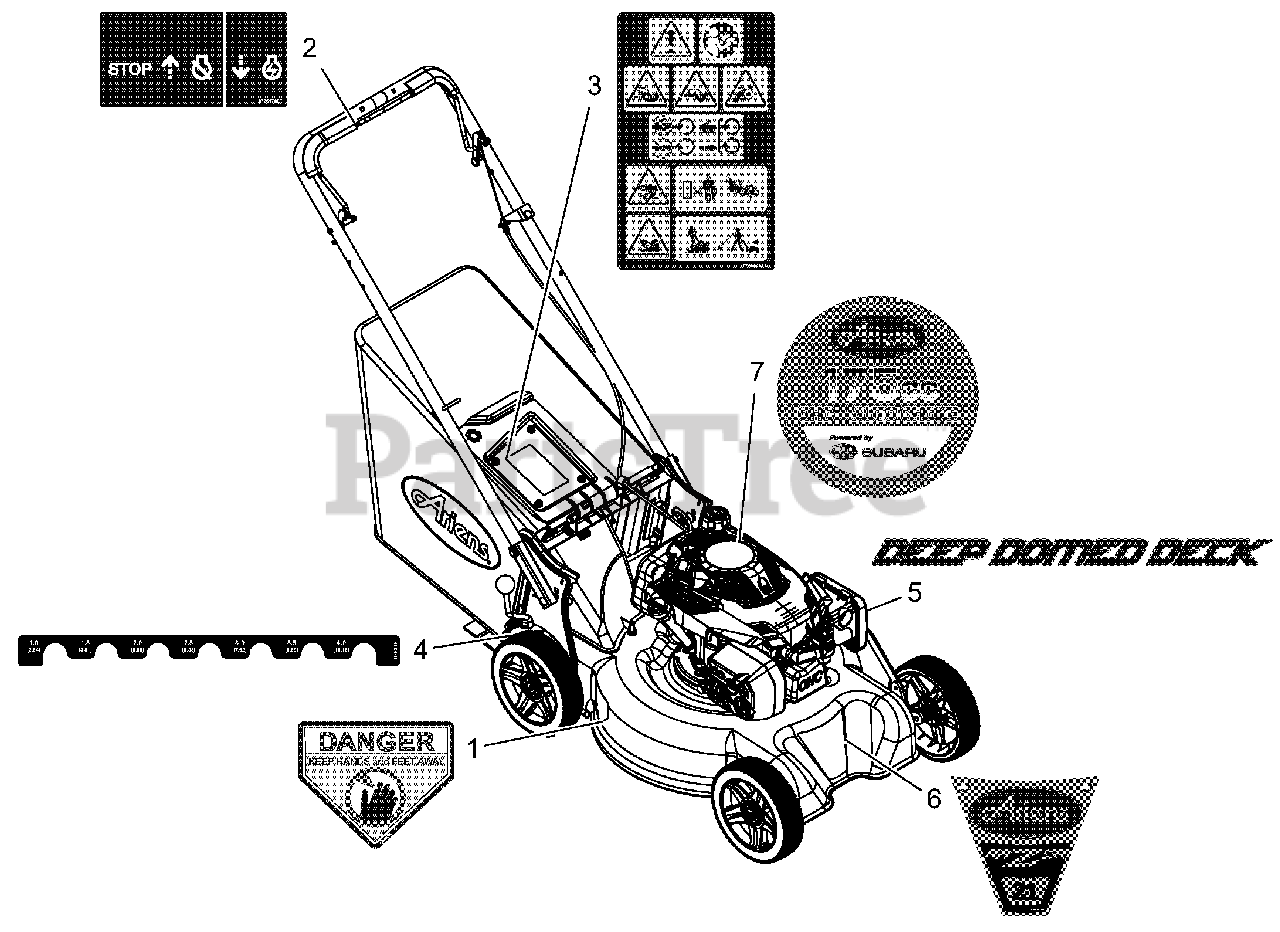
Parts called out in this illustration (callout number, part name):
1	DECAL, DANGER
2	DECAL - ENGINE CONTROL
3	DECAL,MAIN SAFETY_WAW LM
4	DECAL, HOC
5	DECAL, DEEP DOME DECK
6	DECAL, ARIENS RAZOR STYLE
7	DECAL, ENGINE STYLE, ARIENS CE
